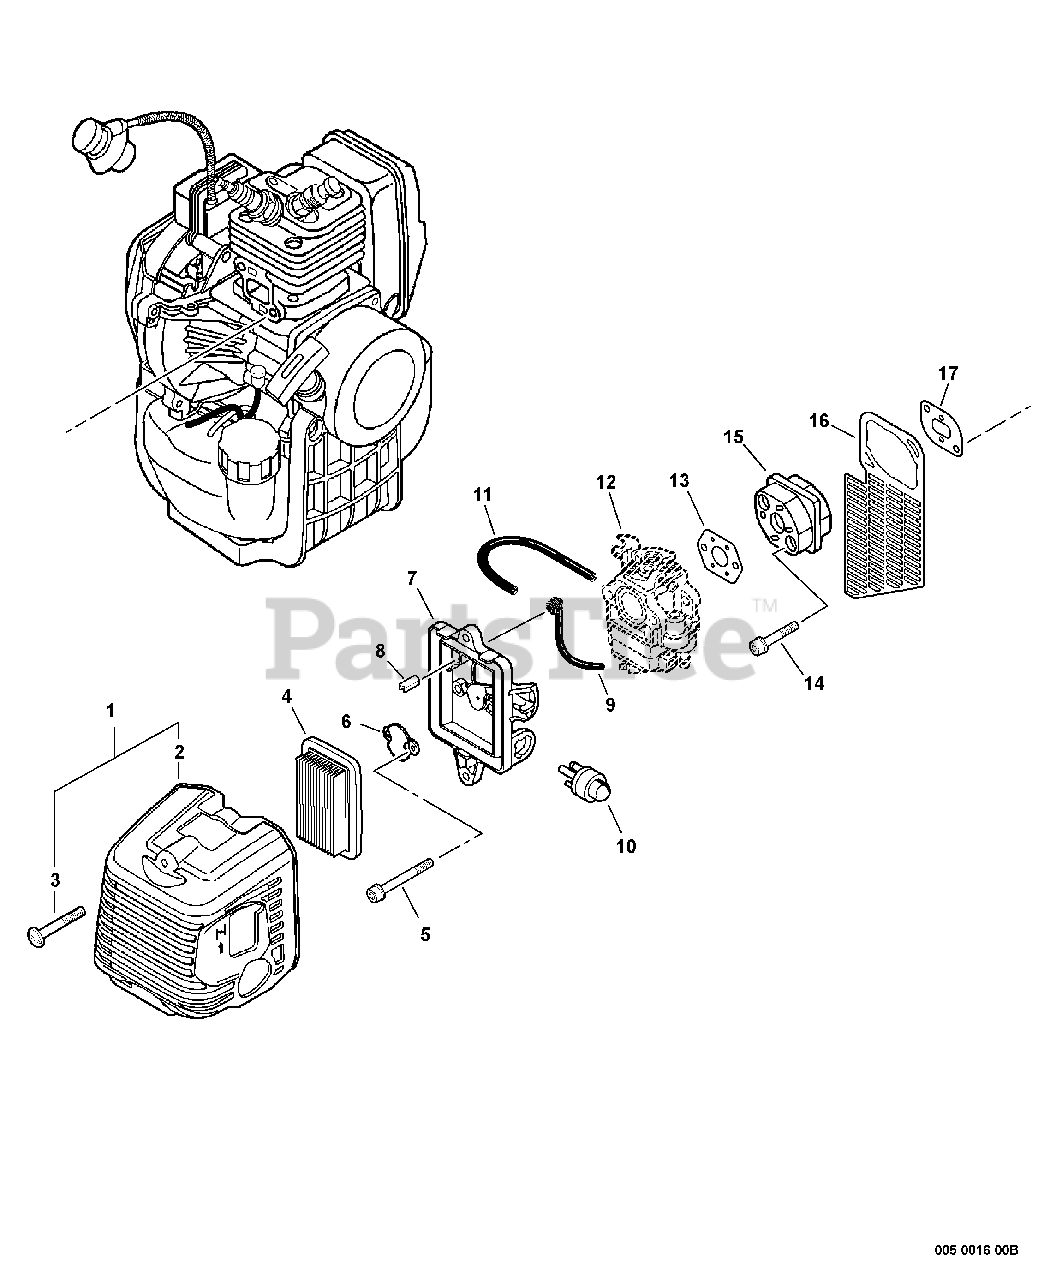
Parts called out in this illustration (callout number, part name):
1	COVER ASSY, AIR FILTER
2	COVER, AIR FILTER
3	SCREW 5×20
4	FILTER, AIR
5	BOLT 5×55
6	PLATE, PREVENT
7	CASE, AIR FILTER
8	PIPE, INTAKE
9	GROMMET, W/VENT PIPE 3×6×105
10	BULB, PURGE
11	PIPE, FUEL 2.4×5×80 BLACK
12	CARBURETOR
13	GASKET, INTAKE
14	BOLT 5×25
15	INSULATOR, INTAKE
16	SHIELD, DEBRIS
17	GASKET, INTAKE
